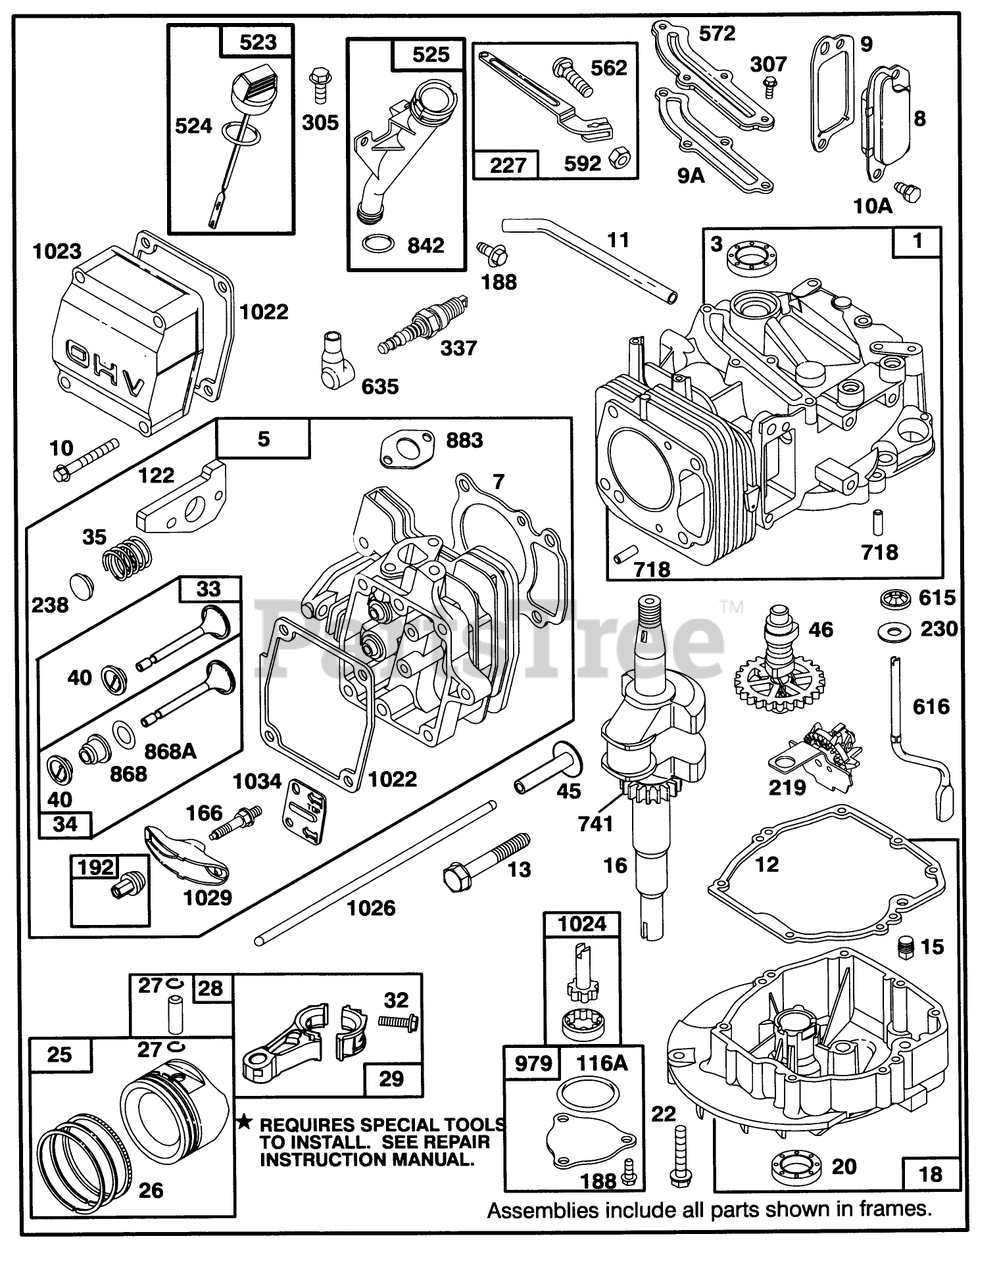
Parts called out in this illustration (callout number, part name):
3	SEAL - OIL
7	CYLINDER HEAD GASKET
9	BREATHER GASKET
9A	GASKET-BREATHER
12	ENGINE BASE GASKET
20	SEAL-OIL
104	FLOAT HINGE PIN
116	SEALING GASKET
116A	O RING SEAL
118	VALVE KIT - NEEDLE
121	CARBURATOR OVERHAUL KIT
122	ADAPTER ASSEMBLY
127	PLUG
134	Valve-Float (Includes Seat)
137	FLOAT BOWL GASKET
163	AIR CLEANER GASKET
358	GASKET SET
524	O-RING
634	SEAL WASHER
842	O-RING
868	SealAssy-Valve
868A	Seal-Valve
883	EXHAUST GASKET
977	CARBURATOR GASKET SET
1022	ROCKER COVER GASKET
1039	FLOAT LIMITER
1041	SEAL - FOAM
